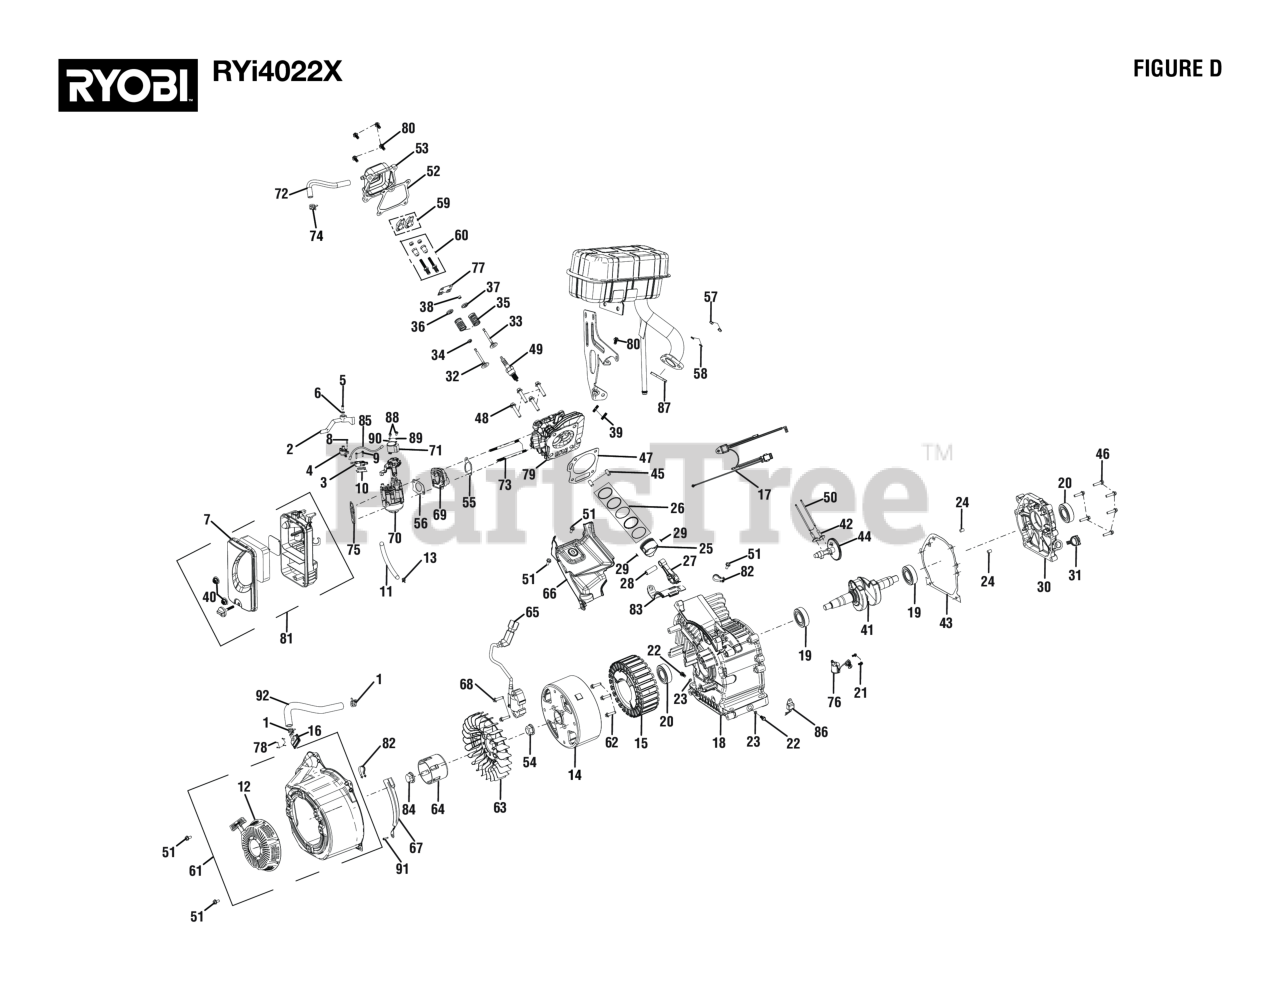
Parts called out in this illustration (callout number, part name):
1	Fuel Hose Pinch Clamp
2	Control Lever
3	Enginge Stop Switch
4	Fuel Valve
5	Screw (M4 x 10 mm, Phillips Pan Hd.)
6	Washer (ID4.3 x OD10 x 0.9t)
7	Engine Air Box Assembly
8	Screw (M6 x 10 mm, Pan Hd.)
9	Screw (St 2.9 x 16 mm, Pan Hd)
10	Engine Switch Bracket
11	Fuel Hose (300 mm)
12	Recoil Starter Assembly
13	Fuel Line Clamp (3/8 in.)
16	Pair Valve
17	Engine Shutdown Wire Harness
18	Crankcase
19	BALL BEARING
20	OIL SEAL
21	Bolt (M6 x 16 mm)
22	BOLT, DRAIN PLUG
23	Drain Plug Washer
24	Casecover Dowel Pin
26	Piston Scraper Ring Set
27	ROD ASSEMBLY,CONNECTING
28	RING, PISTON
29	CLIP, PISTON
30	Crankcase Cover Assembly
32	VALVE, IN
33	VALVE, EXHAUST
34	RETURNER, INTAKE VALVE
35	VALVE, SPRING
36	SEAT, VALVE SPRING, IN
37	SEAT, VALVE SPRING, EX
39	Stud Bolt
40	Hex Nut (M6)
41	Crankshaft Assembly
42	LIFTER, VALVE
43	PACKING, CASECOVER
44	Camshaft Assembly
45	PIN, DOWEL
46	Bolt (M8 x 30 mm)
47	GASKET, CYLINDER HEAD
48	Bolt (M8 x 60 mm)
49	Spark Pulg
50	PUSH, ROD
51	Bolt (M6 x 12 mm)
52	Headcover Packing
53	Cylinder Head Cover
55	PACKING, INTAKE
56	PACKING, CARBURETOR
57	Hex Nut (M8)
58	Spring Washer
59	ROCKER ASSEMBLY
60	Rocker Arm Adujuster
61	Recoil Starter Assembly
62	Bolt (M6 x 45 mm)
63	Recoil StarterFan
64	Starter Pulley
65	Ignition Coil
68	Bolt (M6 x 30 mm)
69	Carburetor Insulator
70	Carburetor Assembly
71	Stepper Motor
72	Breather Tube
74	Fuel Line Clip
75	SPACER, CARBURETOR
76	Oil Level Switch Assembly
77	PLATE, PUSH ROD GUIDE
79	Cylinder Head
80	Bolt (M6 x 16 mm)
81	Air Cleaner Assembly
82	Fuel Line Clamp
85	Flameout Wire
86	Amplifier
88	Bolt (M3 x 8 mm)
89	Spring Washer
90	Flat Washer
91	Bolt (M6 x 20 mm)
92	Pair Valve Hose
